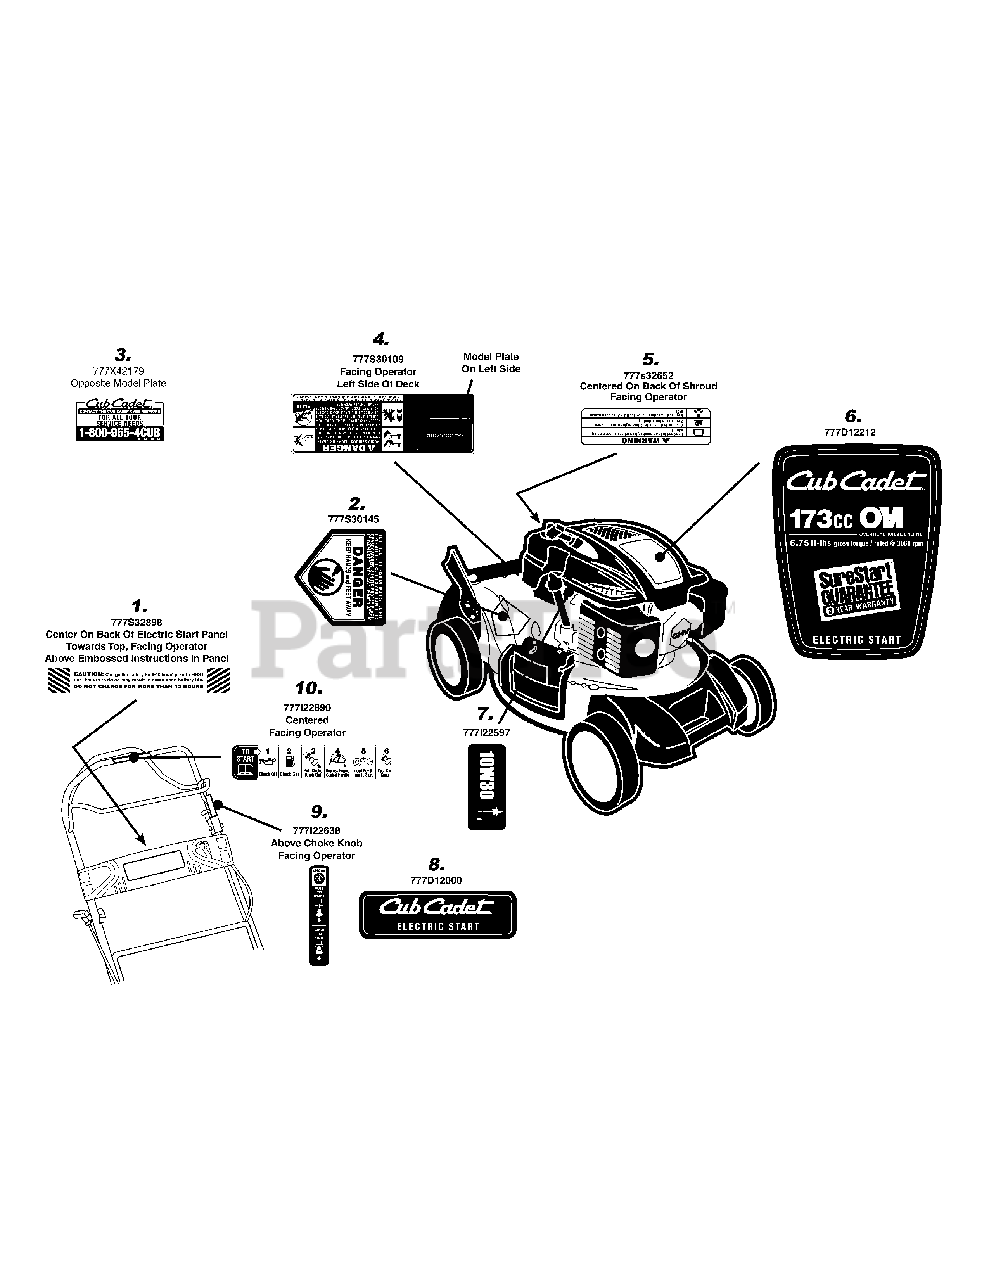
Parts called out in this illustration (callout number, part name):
1	LABEL-MOWER CHARGE CAUTION
2	LABEL
3	LABEL-CUB HOTLINE
4	LABEL-MOWER DANGER
5	LABEL:MOWER:ENGINE SHROUD
6	LABEL-173CC SHROUD OHV ELEC
7	LABEL:MOWER SHROUD
8	LABEL-ELEC START CUB CADET
9	LABEL-MOWER HANDLE:CHOKE START
10	LABEL-STRT INSTRUCT
